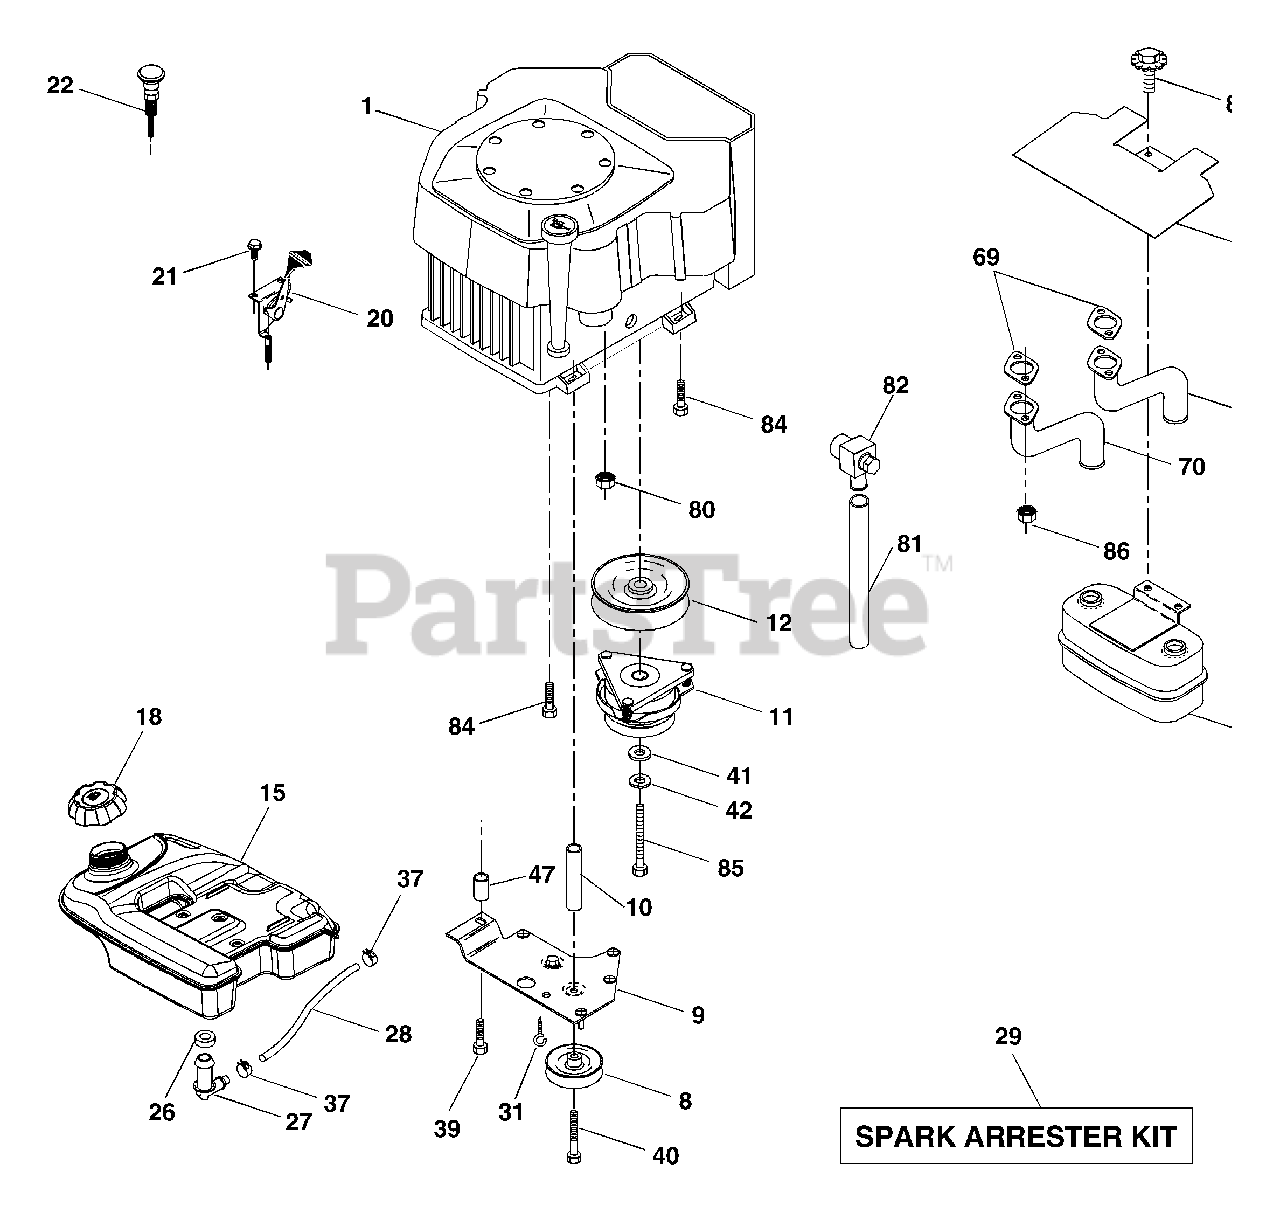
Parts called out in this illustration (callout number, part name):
2	Muffler Side
8	Pulley V-Idler
9	Keeper Asm. Belt Engine VGT
11	Clutch Electric
12	Pulley Engine VGT Elect Clutch
15	Tank Fuel 5.0
18	Cap Fuel
20	Control Throttle
21	Screw HWHD Hi-Lo #13-16 x 3/4
22	Control Choke
26	Bushing
27	Stem Tank Fuel
28	Fuel Line
29	Spark Arrester Kit
31	Clip Push-In
37	Clamp Hose
39	Screw TT 3/8-16 x 2-1/4 unc
40	Screw TT 3/8-16 x 4 unc
41	Washer 1-1/2 OD x 15/32 ID x .250
42	Washer Lock 7/16
62	Shield Heat Muffler
69	Gasket
70	Tube Exhaust LH
71	Tube Exhaust RH
80	Nut Flange M8-1.25
81	Tube Drain Oil
82	Valve Oil Drain
83	Bolt 5/16-18unc x 1-3/4 W/Sems
84	Screw 3/8-16 x 1-1/2
85	Bolt Hex 7/16-20 x 3.75 Ga 5
86	Nut Hex Flange Toplock M8-1.25
